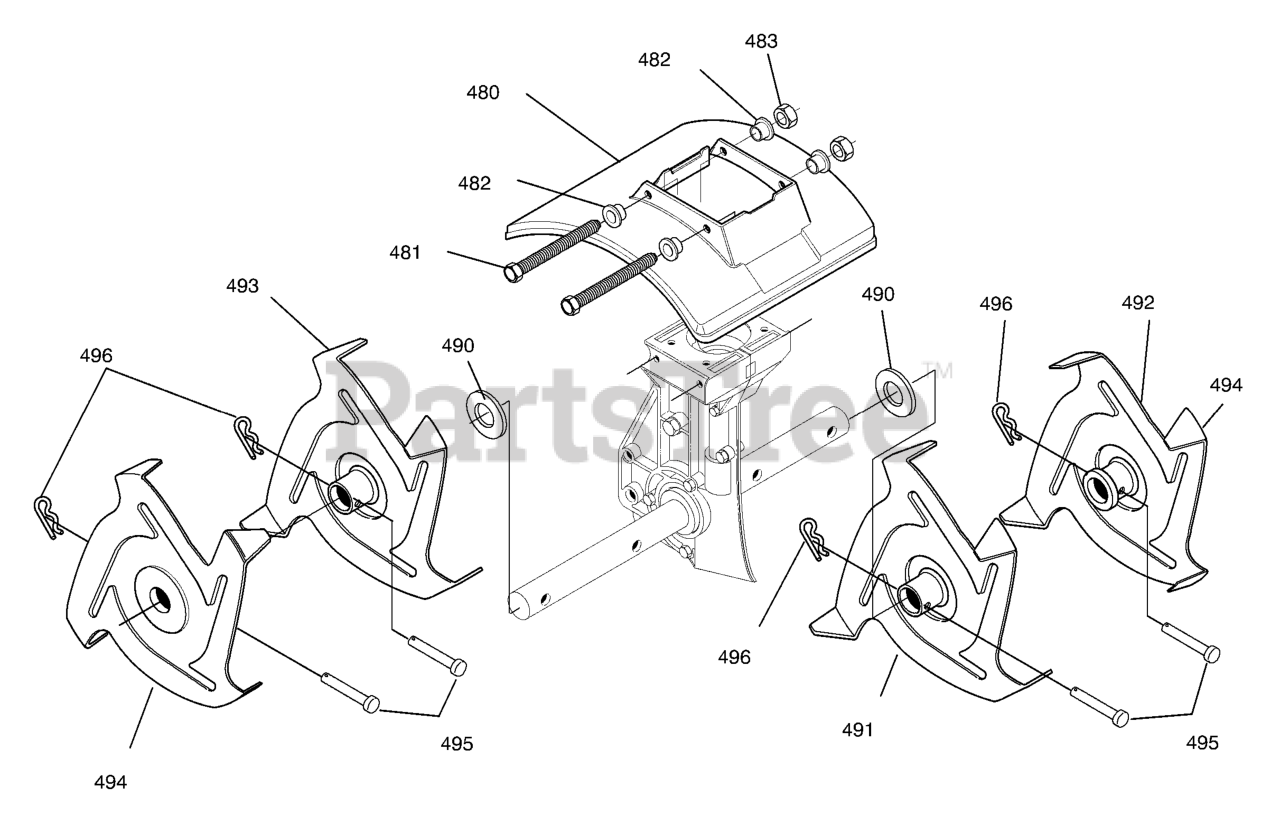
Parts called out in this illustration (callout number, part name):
480	Shield, Tine
481	Screw, 1/4-20x5.50
482	Spacer, Flange
483	Nut, 1/4-20
490	Washer, Felt
491	Tine Assy. Inner LH
492	Tine Assy. Outer LH
493	Tine Assy. Inner RH
494	Tine Assy. Outer RH
495	Clevis Pin
496	Hair Pin
